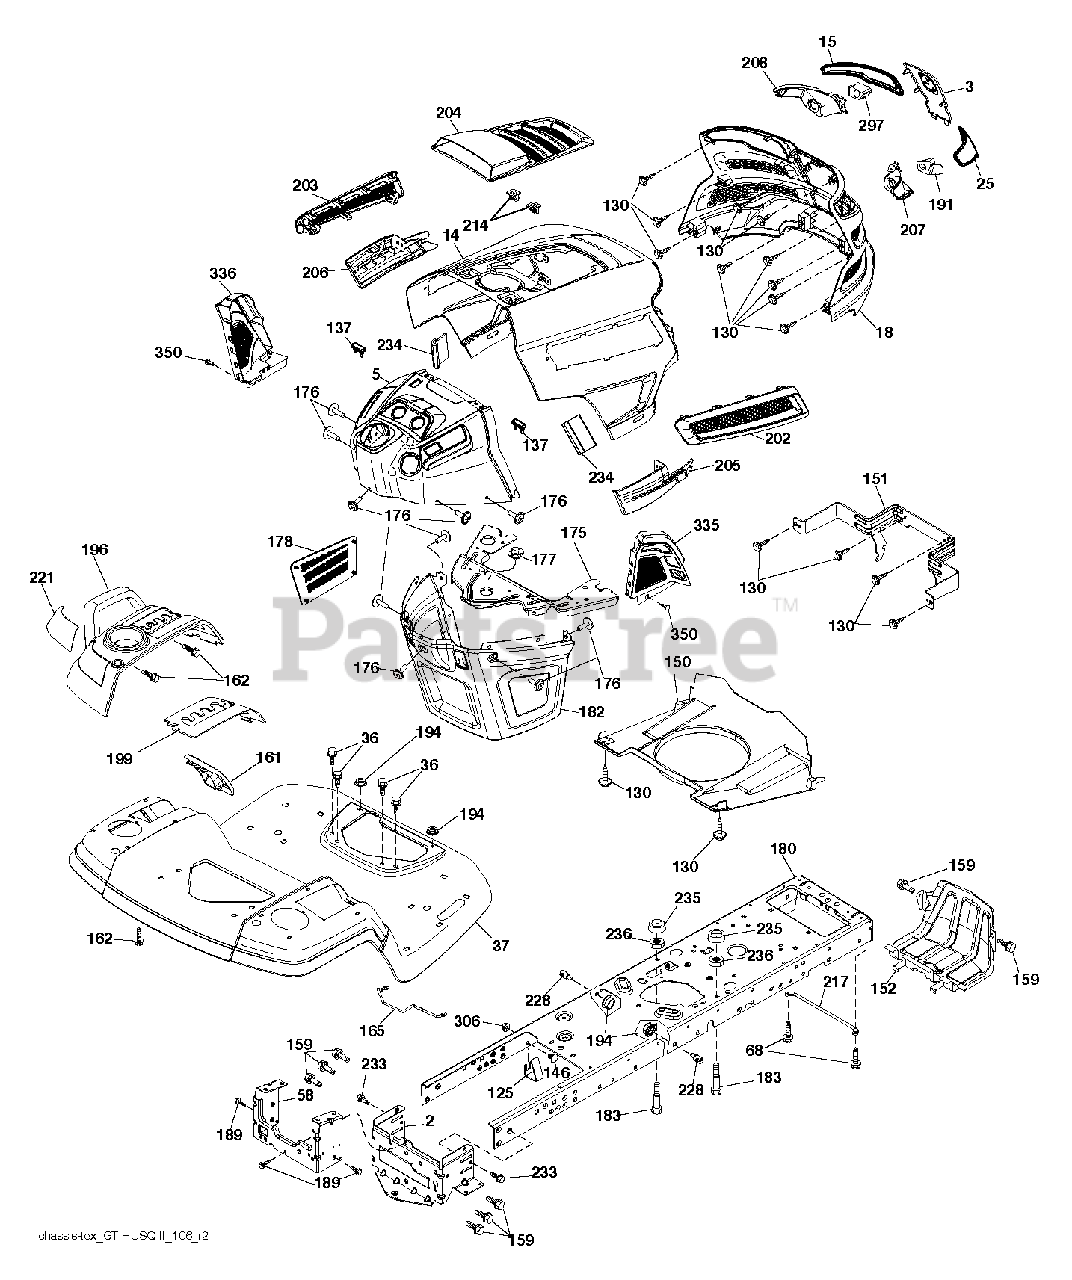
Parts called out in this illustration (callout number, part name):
2	DRAWBAR.LOWER.2PC.18/22
3	APPLIQUE.SUBASM.GT.HUSQ.II
5	DASH.UPP.GT2.DR.PTO.DCKLFT.MC
14	HOOD.ASM.HUSQVARNA.GT.TEX.ORAN
15	LENS.HEADLIGHT.LH.GTII.2011
18	GRILLE.SUBSTRATE.2011.
25	LENS.HEADLIGHT.RH.GTII.2011
36	SCREW 5/16"
37	FENDER.PNT.TX.GT.CH/FW/DL.HUSQ
58	DRAWBAR.UPPER.2PC,LRG.FENDER
68	SCREW LT
125	CLIP.FUEL.LINE
130	SCREW.#10 X 0.750.BOS
137	BUMPER DASH
146	BOLT.RDHD.SHT.SQNK.3/8-16X5/8
150	AIR.DUCT.GTV.BLACK
151	BRACKET.PIVOT.HOOD.GT.HUSQ.II
152	SHIELD.BROWNING.PNT.GT.V2
159	SCREW, 3/8-16X3/4
161	CONSOLE.WINDOW.FUEL.HUSQ.GT
162	SCREW.HI-LO.CONSOLE
165	SUPPORT.TANK.REAR.B/TE
175	PLATE.CROSSMEMBER.HUSQ
176	SCREW.#10-24X5/8.RN.QU
177	BUSHING, STEERING
178	CARGO.ASM.NET.TXGT.W/C
180	CHASSIS.TEX.BOLTED
182	DASH.LOWER.COMMON.12V.ADAPTOR
183	BOLT.5/16-18X1-1/4 FULL THD
189	SCREW
191	INSERT.REFLECTIVE.RH.HUSQ.GTII
194	NUT LOCK HEX FLANGE 5/16-18
196	CONSOLE.ASM.DECKLIFT.HUSQGT.DL
199	PLATE.DECK.LIFT.HUSQVARNA.GT
202	VENT.SIDE.RH.GT.HUSQ.II.
203	VENT.SIDE.LH.GT.HUSQ.II.498
204	VENT.TOP.HUSQ.GT2
205	SIDE.TRIM.RH.GT.HUSQ.II
206	SIDE.TRIM.LH.GT.HUSQ.II.GRAY
207	BEZEL LIGHT.RH.GT.II.MYLAR
208	BEZEL LIGHT.LH.GT.II.MYLAR
214	CLIP.RETAINER.TINNER.
217	ROD.PIVOT.HOOD
221	REFLECTOR.LH.TEX GT HU
228	STUD.FASTNER.W/ANTI-ROTATE
233	BOLT.SHOULDER
234	BUMPER.HOOD.TEX.HUSQVARNA
235	SPACER FENDER
236	NUT.CENTERLOCK.5/16-
297	INSERT.REFLECTIVE.LH.HUSQ.GTII
306	NUT LOCK FLG 3/8-16 UNC
335	COVER.LOWER.DASH.RH.BLACK
336	COVER-LH.LOWER.DASH.GT2.BLACK
350	CLIP.X-MAS.TREE
